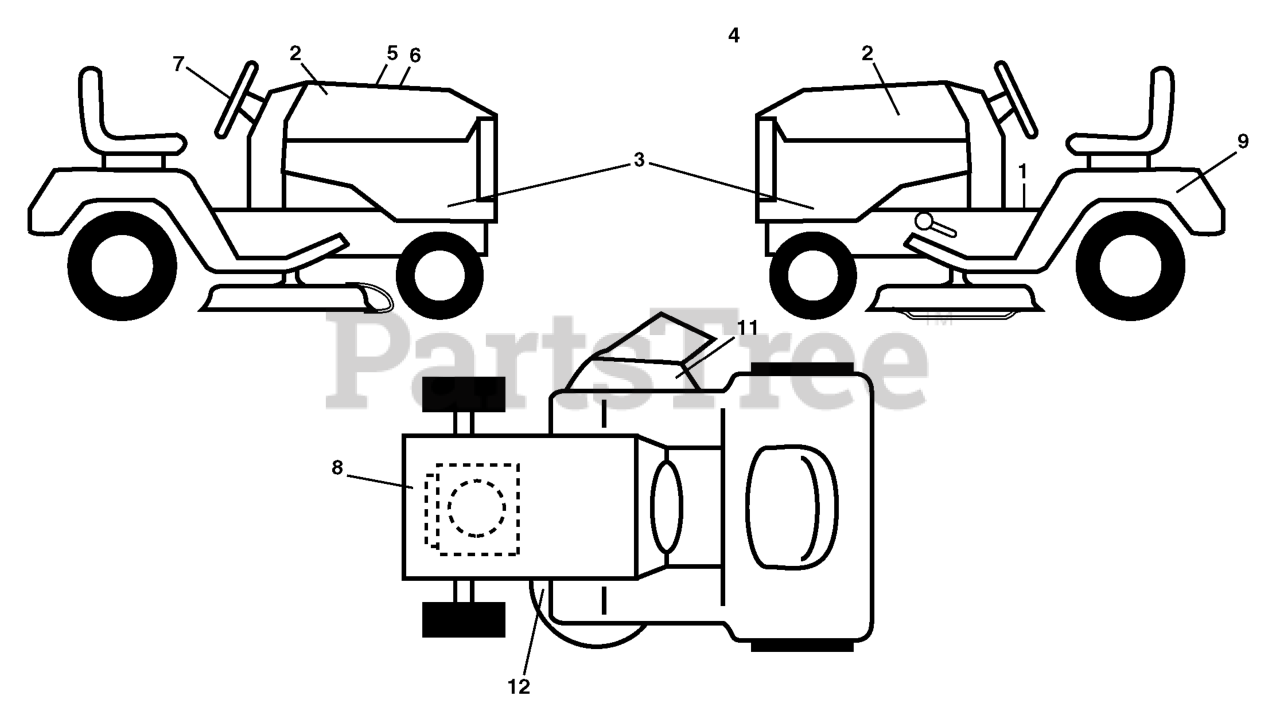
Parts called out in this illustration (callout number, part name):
1	DECAL.FENDER.OPER.TEX.
2	DECAL.HOOD.NAMELOGO.HUSQ
3	DECAL.PANEL.SD.YTH2242
4	DECAL.HOOD.TOP.INSERT.
5	DECAL HOOD CUST. RESP.
6	DECAL.RPL.B&S.22
7	DECAL.WHEEL.STRG.LGN.H
8	DECAL.B&S.22HP#275796
9	DECAL BTRY SYMBOLS
11	DECAL.WARN.KEEP.HAND.AWAY
12	DECAL V BELT SCHEMATIC
